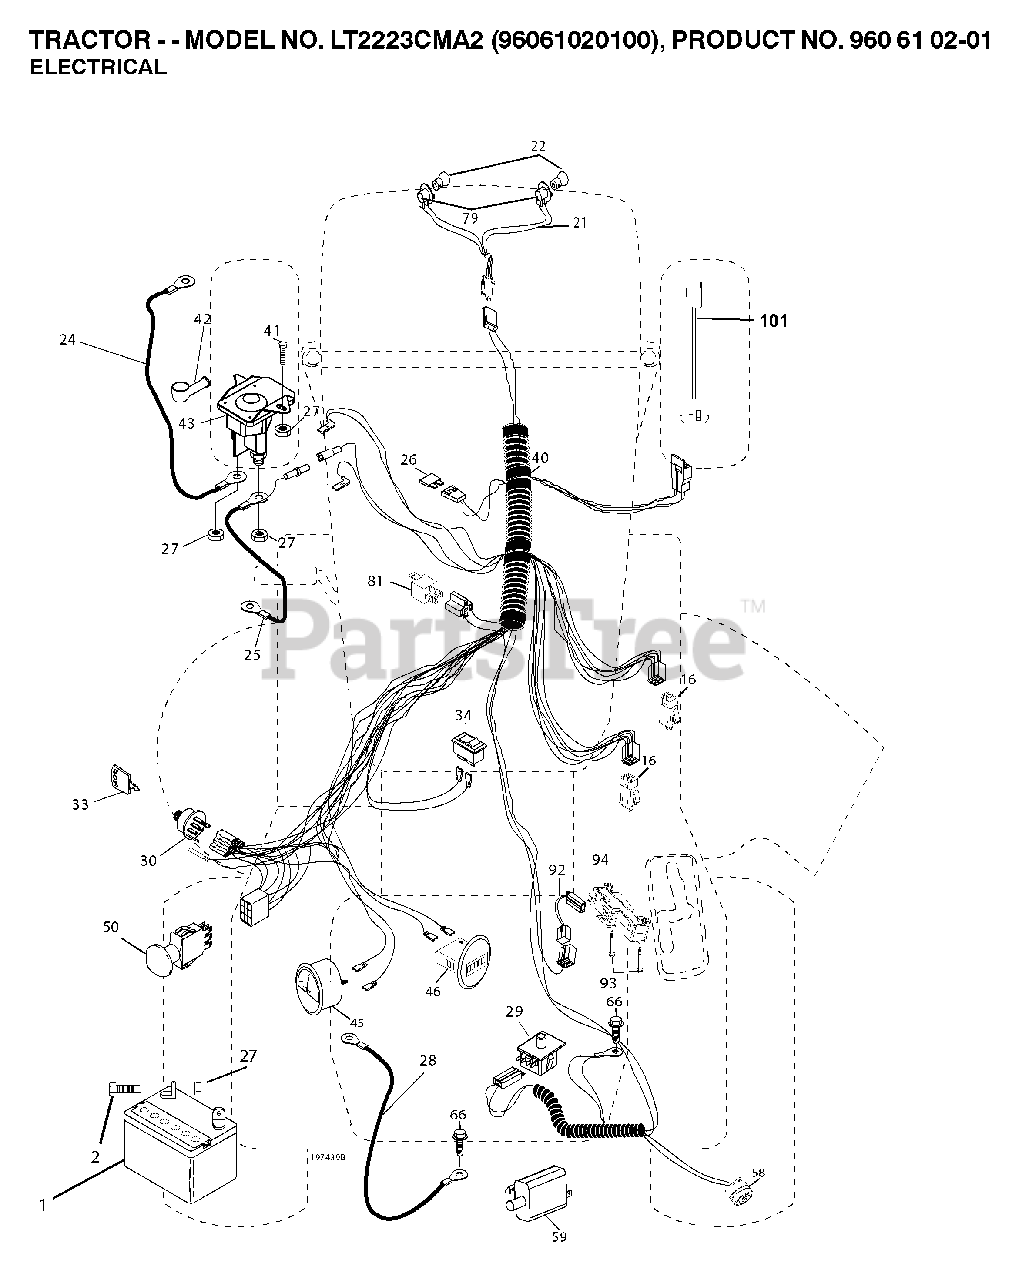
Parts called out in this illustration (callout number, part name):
1	BATTERY 12V .35 AMP
16	SWITCH INTERLOOK PUSH-IN
21	HARNESS.W/LIGHT SOCKET
22	LIGHTBULB
24	BATTERY CABLE GT
25	CABLE BATTERY
26	FUSE 20AMP
27	NUT
28	CABLE GROUND
29	SWITCH.SEAT.DP W/RAMPS
30	SWITCH.IGN.DELTA.W.LGH.ROS
33	KEY MLD GEN DELTA
34	SWITCH LT
42	TERMINAL COVER
43	SOLENOID.W/BRASS.PLUNG
46	HOURMETER SNAP-IN
50	PTO SWITCH
58	BUZZER
79	BULB HOLDER ASM.
81	RELAY.ASSY.T
92	HARNESS.PIGTAIL.CONSLE
93	SCREW.PLASTITE
94	MODULE.REVERSE.ROS
101	PIGTAIL.MATNLK.NEW.HAR
